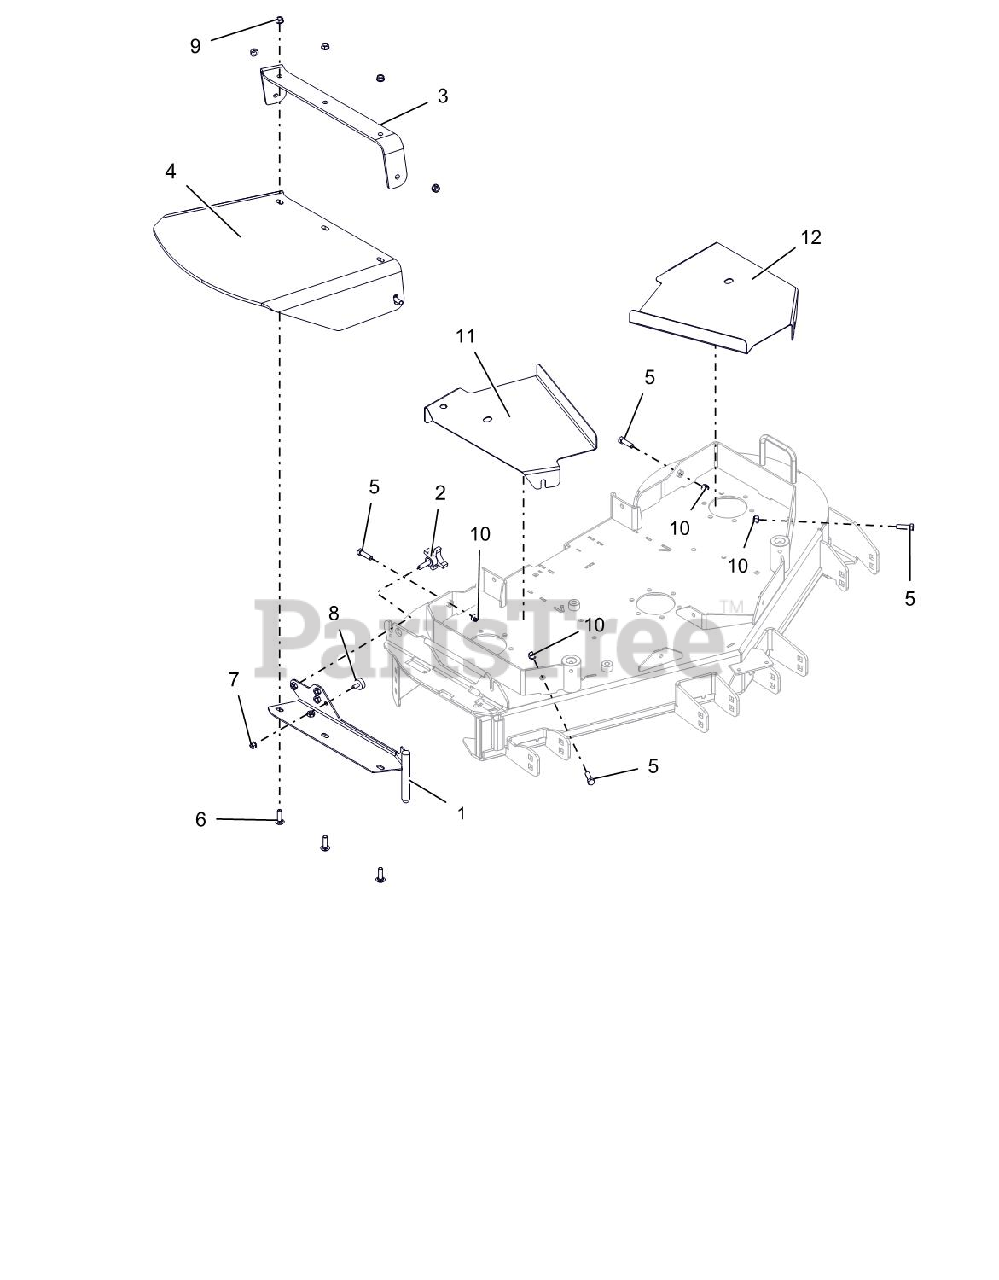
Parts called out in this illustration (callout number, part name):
1	WLDT. DISCHARGE
2	KNOB, 3/8 X 1.25 - 4 PRONG
3	STRAP, GRAVELY WLK RUBBER DIS
4	SHIELD, WALK RUBBER DISCHARGE
5	BLT, HEX .38-16X1.25 G5 ZCC
6	BLT,RHSSN-.375X1.25 G5 RIE5230
7	NUT,SPNLK-FLG .312-18 ZC120
8	BUMPER, RUBBER
9	NUT, SPNLK-FLG .38-16 G5ZC120
10	NUT,NYL .38-16 G5 ZCC
11	COVER, RH 48" BELT
12	COVER, LH 48"
